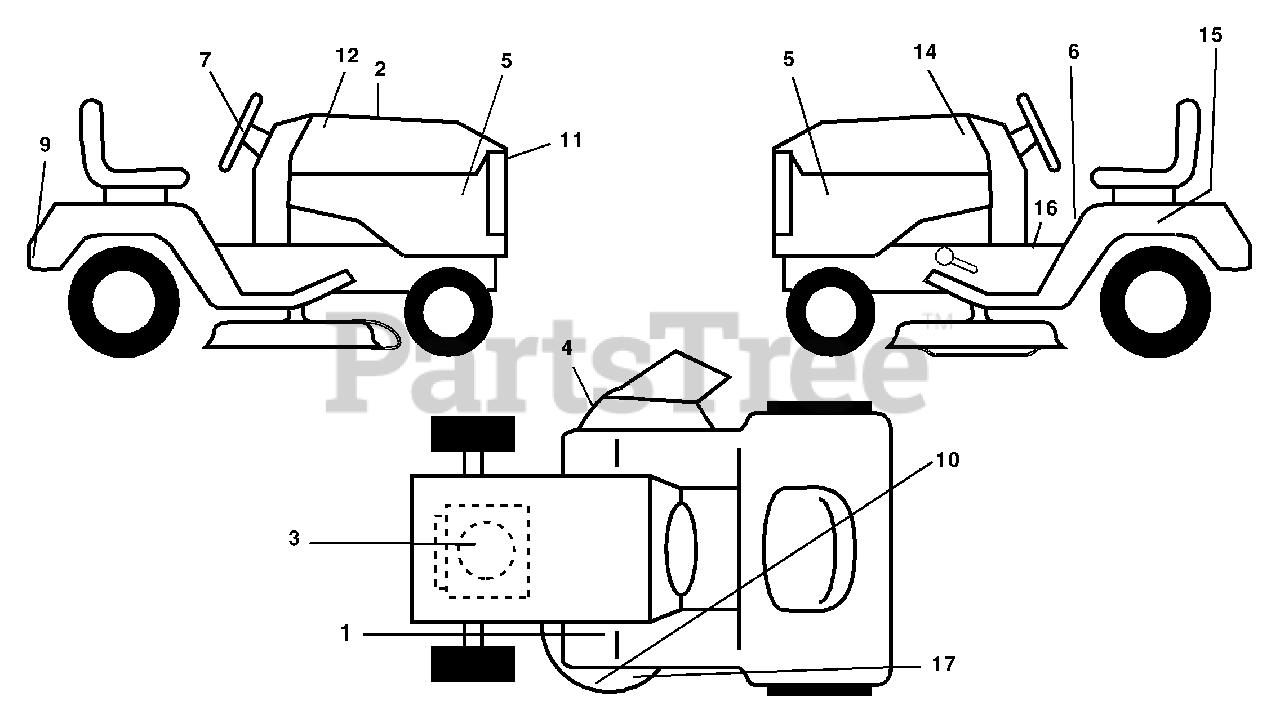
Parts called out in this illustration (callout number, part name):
1	Decal, Clutch/Brake Eng/Fr
2	Decal, Replacement
3	Decal, Engine HP
4	Decal Warning
5	Decal, Pnl Sd
6	Decal, Fender Danger English
7	Decal Ins Str Wh
9	Decal Fender
10	Decal, Deck Grasseater
11	Decal, Grille Weedeater
12	Decal, Hood RH
14	Decal, Hood LH
15	Decal, Caution, Battery
16	Decal, Oper Sdl P/L Gear Dr Eng
17	Decal, V-Belt Sch.
